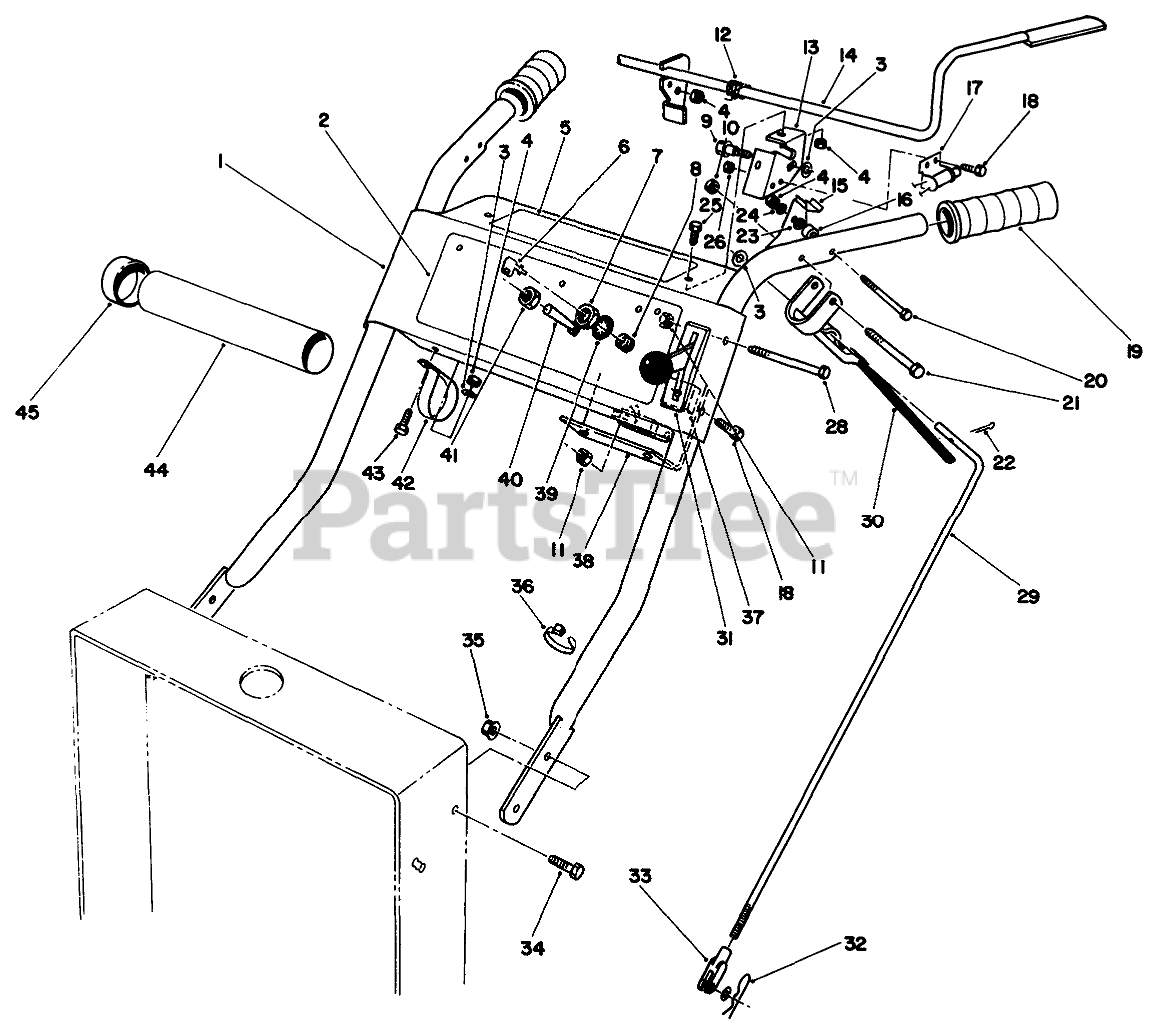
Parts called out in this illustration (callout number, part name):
1	HANDLE WA R
2	DECAL- CONTROL PANEL
3	WASHER-PLAIN
4	NUT-LOCK, NI
5	DECAL - INSTRUCTION
6	KEY-IGNITION
7	NUT-HH
8	Switch (Incl. Ref. #7 & 39)
9	BOLT-SHOULDER
10	NUT-LOCK, NI
11	NUT-LOCK, NI
12	TORSION SPRING
13	INTERLOCK MTG BRKT B
14	INTERLOCK BAIL WA B
15	LH NEUTRAL BRACKET
16	Spacer-Latch
17	DECK INTERLOCK SWITCH
18	SCREW-HWH
19	HANDLE GRIP
20	SCREW-HH
21	SCREW-HH
22	PIN-COTTER
23	WASHER
24	WASHER-BELLEVILLE
25	SCREW-HH
26	NUT-KEPS
28	SCREW-SHH
29	CONTROL ROD
30	LIFT BAIL WA
31	THROTTLE-CONTROL
32	PIN-COTTER
33	CLEVIS-ADJ
34	SCREW-HHF
35	NUT-HF
36	TIE-CABLE
37	RECTIFIER-BRIDGE
38	SWITCH COVER R
39	WASHER-TOOTH, INTERNAL
40	Switch-Clutch (Incl. Ref. #41)
41	NUT
42	CLAMP-R
43	SCREW-HH
45	CAP-END
